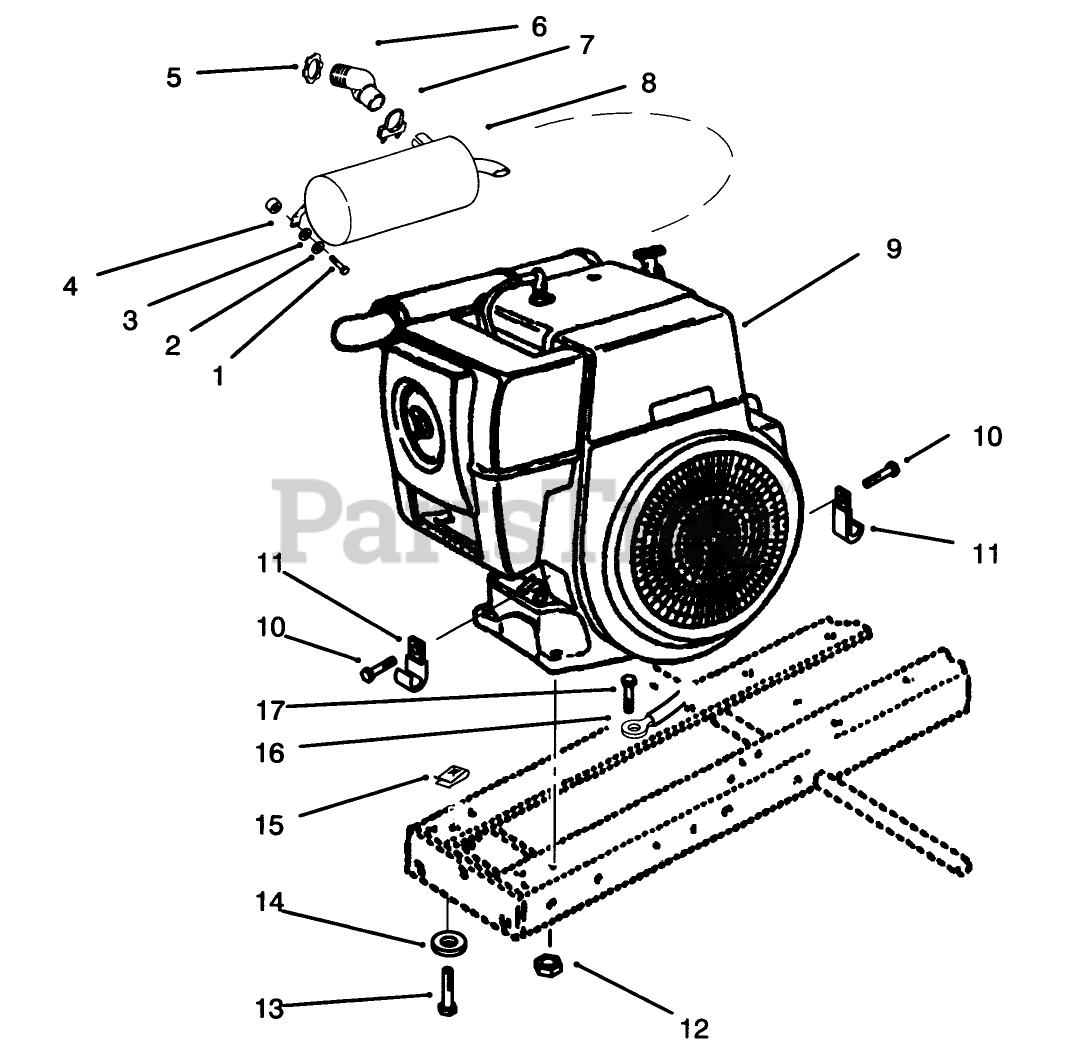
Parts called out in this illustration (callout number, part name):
1	SCREW-HH
2	WASHER-LOCK
3	WASHER-PLAIN
4	SPACER
5	KOHLER AC-1536
6	KOHLER47-054-01
10	Screw (Engine) Ref.
11	CLIP
12	NUT-LOCK, NI
13	SCREW-HH
14	WASHER-LOCK
16	WIRE GROUND
17	SCREW-HH
